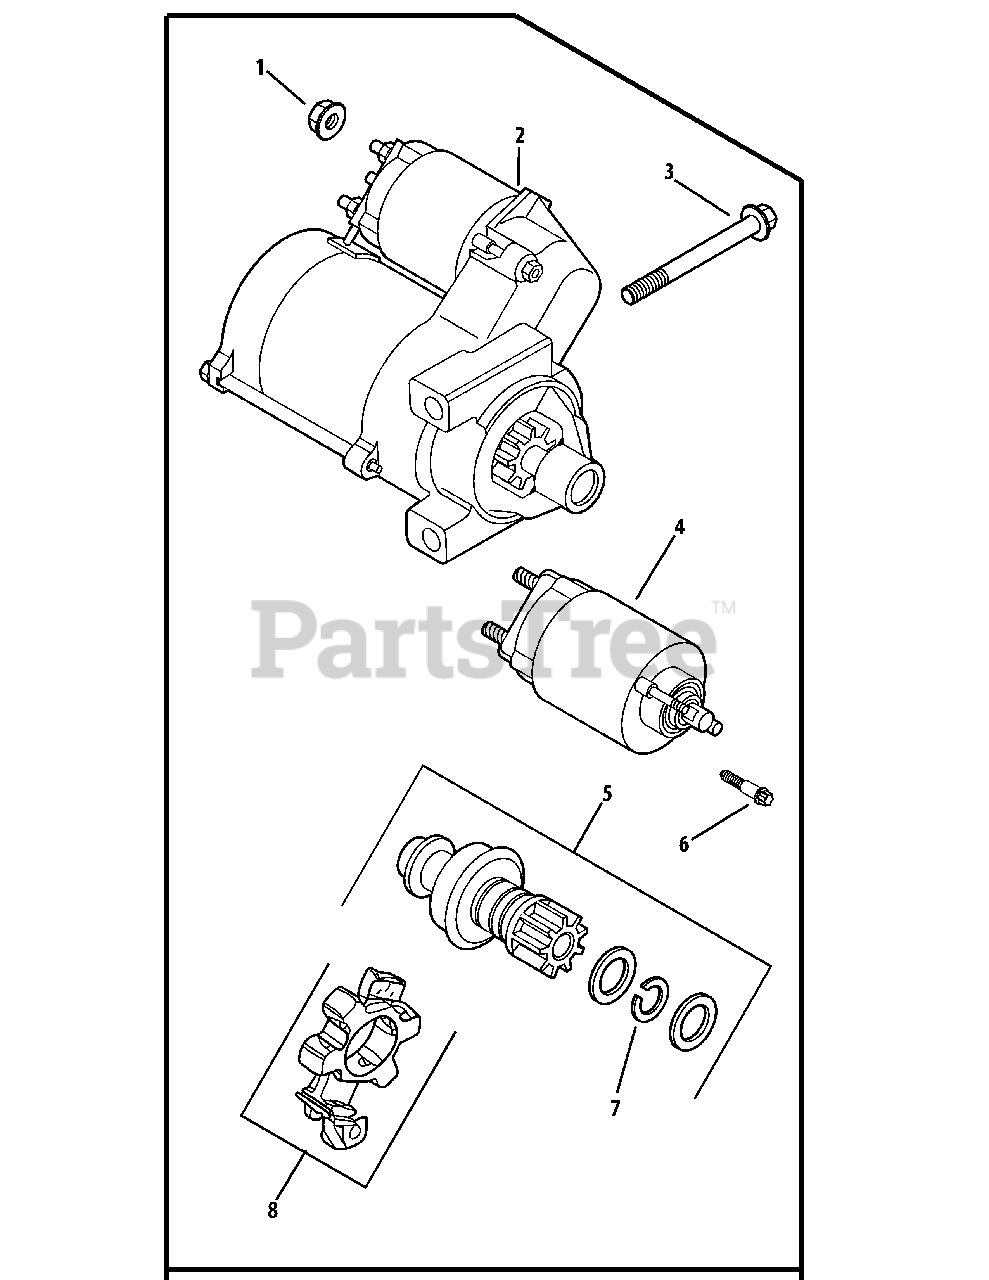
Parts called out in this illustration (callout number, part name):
1	Flange Nut, M8 x 1.25
2	Electric Starter (Solenoid Shift)
3	Flange Screw, M8 x 1.25 x 80
5	Starter Pinion Kit
6	External Torx Head Screw
7	Retaining Ring
8	Brush Holder Kit
